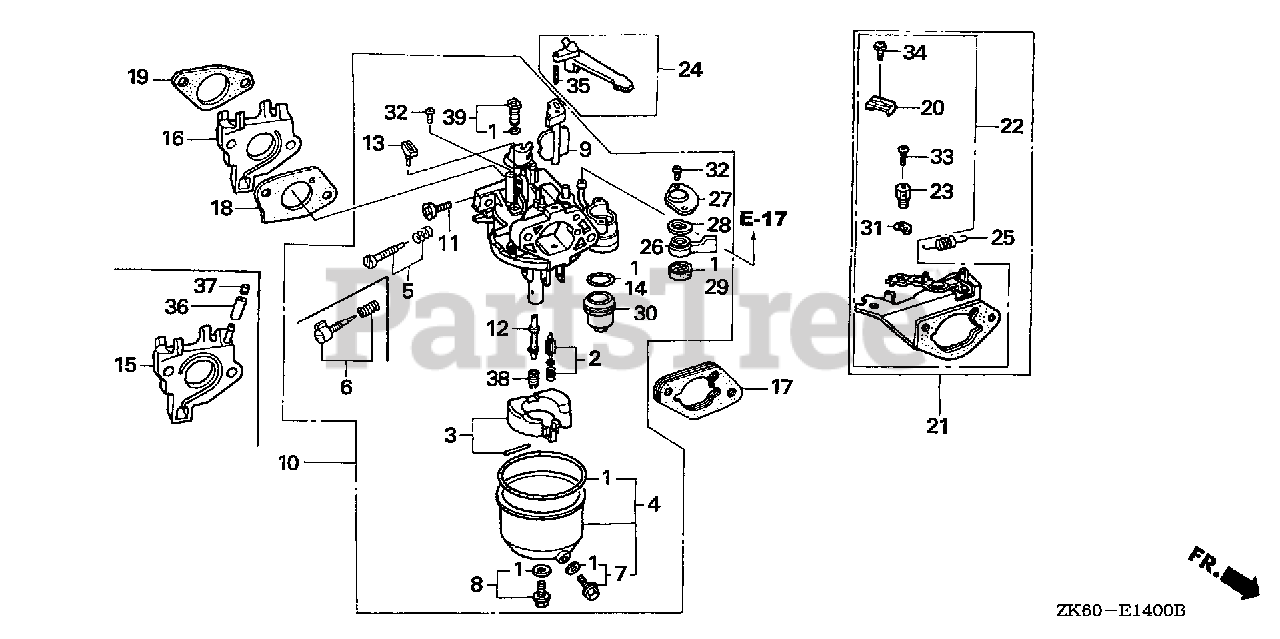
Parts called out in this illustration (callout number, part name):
1	GASKET SET (INCLUDES 16173-001-004)
2	VALVE SET, FLOAT
4	CHAMBER SET, FLOAT
6	SCREW SET, PILOT (CARBURETOR NO.)
7	SCREW SET, DRAIN
8	SCREW SET
10	CARBURETOR ASSY. (BE85B B)
11	SCREW, THROTTLE STOP
12	NOZZLE, MAIN
13	COLLAR, SETTING
14	GASKET, FUEL STRAINER CUP
16	INSULATOR, CARBURETOR
18	GASKET, CARBURETOR
19	GASKET, INSULATOR
20	HOLDER, CABLE
21	STAY ASSY., CHOKE CONTROL (REMOTE)
23	HOLDER, WIRE
25	SPRING, RETURN
26	LEVER, PETCOCK
27	PLATE, LEVER SETTING
28	SPRING, PETCOCK LEVER
29	GASKET, PETCOCK
30	CUP, FUEL STRAINER
31	CIRCLIP (5MM)
32	SCREW, PAN (3X6)
33	SCREW, PAN (4X6)
34	SCREW-WASHER (5X16)
38	JET, MAIN (#88)
38	JET, MAIN (#90)
38	JET, MAIN (#92)
39	JET SET, PILOT (#45)
